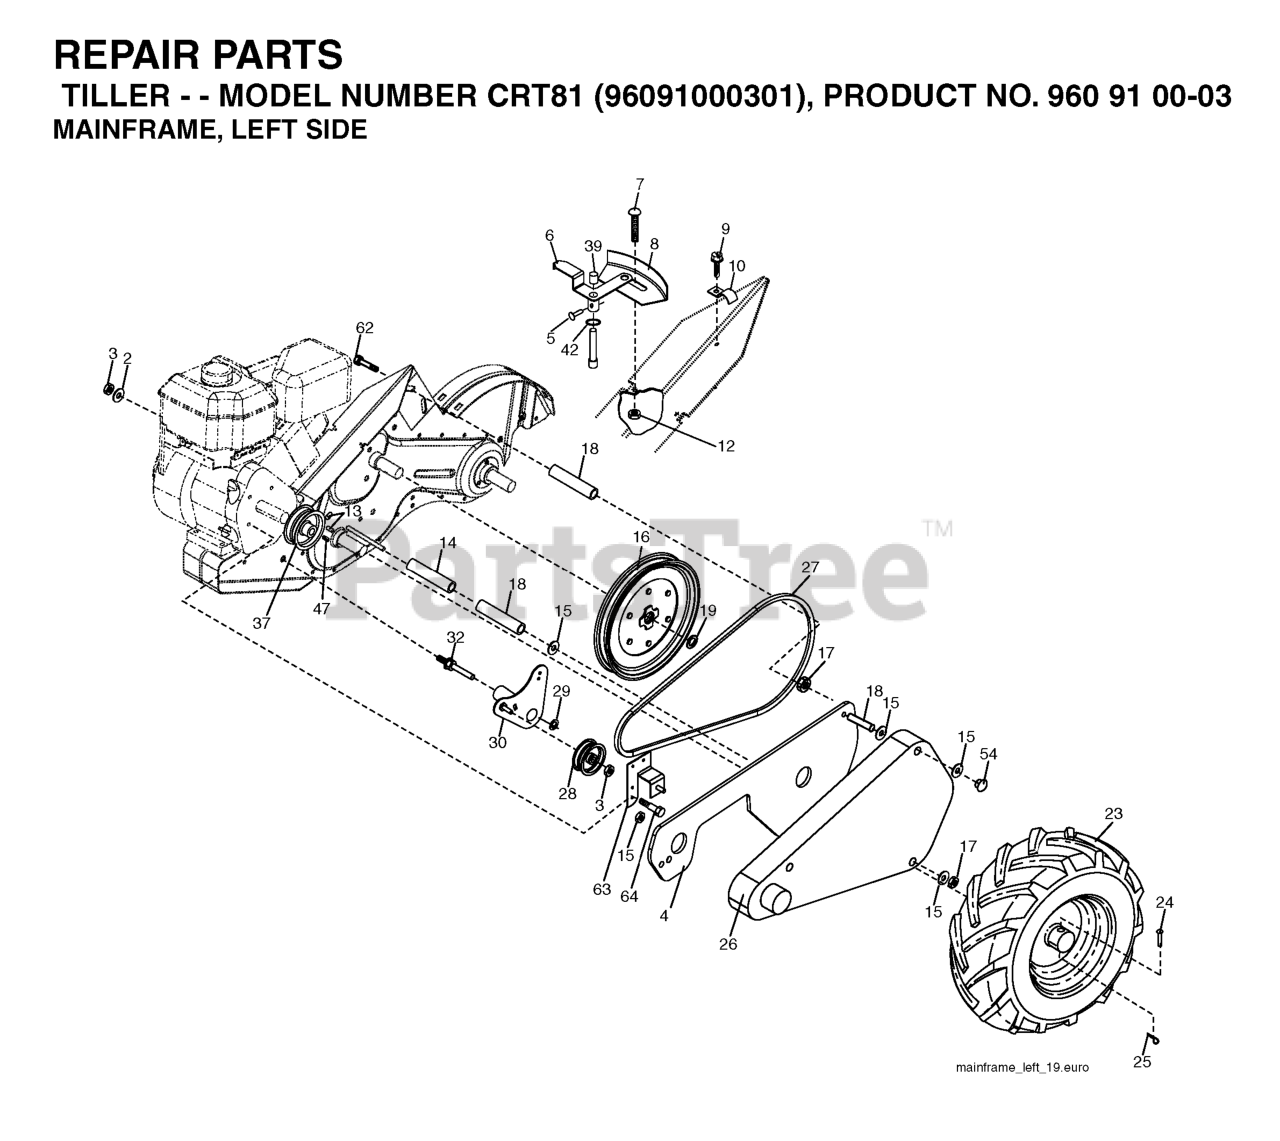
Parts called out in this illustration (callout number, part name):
2	WASHER, LOCK 3/8
3	NUT.HEX.3/8-16UNC
4	Shield, Inner Belt Guard RT
5	PIN.SPIROL.FLARED
6	LEVER ASM CRT
8	PANEL.INDICATOR.SHIFT.BLACK
9	TAPPING SCREW
10	CONDUIT.CLIP.PLATED
12	NUT
14	SPACER-SPLIT.327 X .42
15	WASHER
16	SHEAVE, TRANSMISSION
18	SPACER SPLIT
19	RETAINING RING LT
23	TIRE.16X4-8.CHEVRON.TILLER
25	SPRING TI
26	FOOTREST.PNT.LH
27	BELT, DRIVE
28	PULLEY-IDLER TI
30	BRACKET.ASM.IDLER.BLACK
32	SHAFT, IDLER ARM
37	SHEAVE, ENGINE
39	CAP.PLUNGER.BLACK
47	KEY, SQUARE
62	BOLT 5/16-18X4 1/2
63	Bracket Asm Guard
